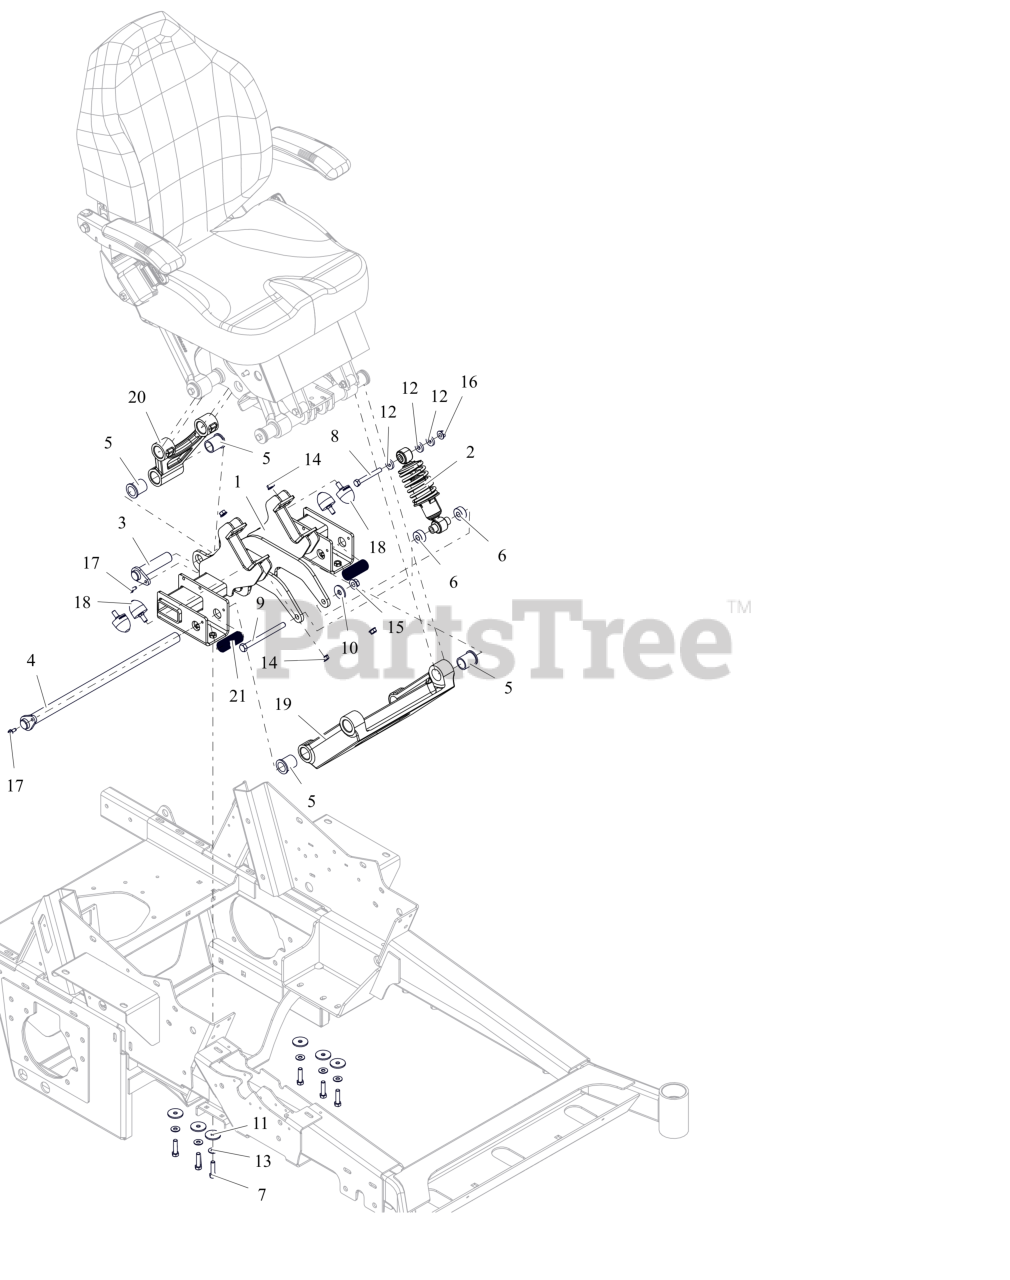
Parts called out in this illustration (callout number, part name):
1	WLDMT, SUSPENSION MTG (RED)
2	SHOCK, LOWER - TENNECO
3	WLDMT, LOWER REAR PIVOT SHAFT (RED)
4	WLDMT, LOWER FRONT PIVOT SHAFT (RED)
5	BEARING, SINTERED BRONZE FLANGE
6	SPCR, .400 x 1.250 x .513
7	BLT, HEX 0.375-16X1.5 GR8 ZCC
8	BLT,HEX M10-1.5X80 G10.9 ZCC
9	BLT,HEX M12-1.75X140 G10.9 ZCC
10	WSHR-FL-STL.511X1.44X.125ZC120
11	WSHR, FLT .380X1.50X.125 ZCC
12	WSHR, FLT .406X1.00X.188 ZCC
13	WSHR, HDND 0.375X0.875X0.064 ZCC
14	NUT-LK-CTR-FLG .375-16 GF ZCC
15	NUT, FLG-CTR LK M12-1.75 ZCC
16	NUT, FLG-CTR LK M10-1.50 ZCC
17	SCR,TAP .25-20X.625 HWH ZCC
18	BUMPER, CONICAL
19	MACHINED, FRONT LOWER LINK
20	MACHINED, REAR LOWER LINK
21	SLEEVE, SHAFT
